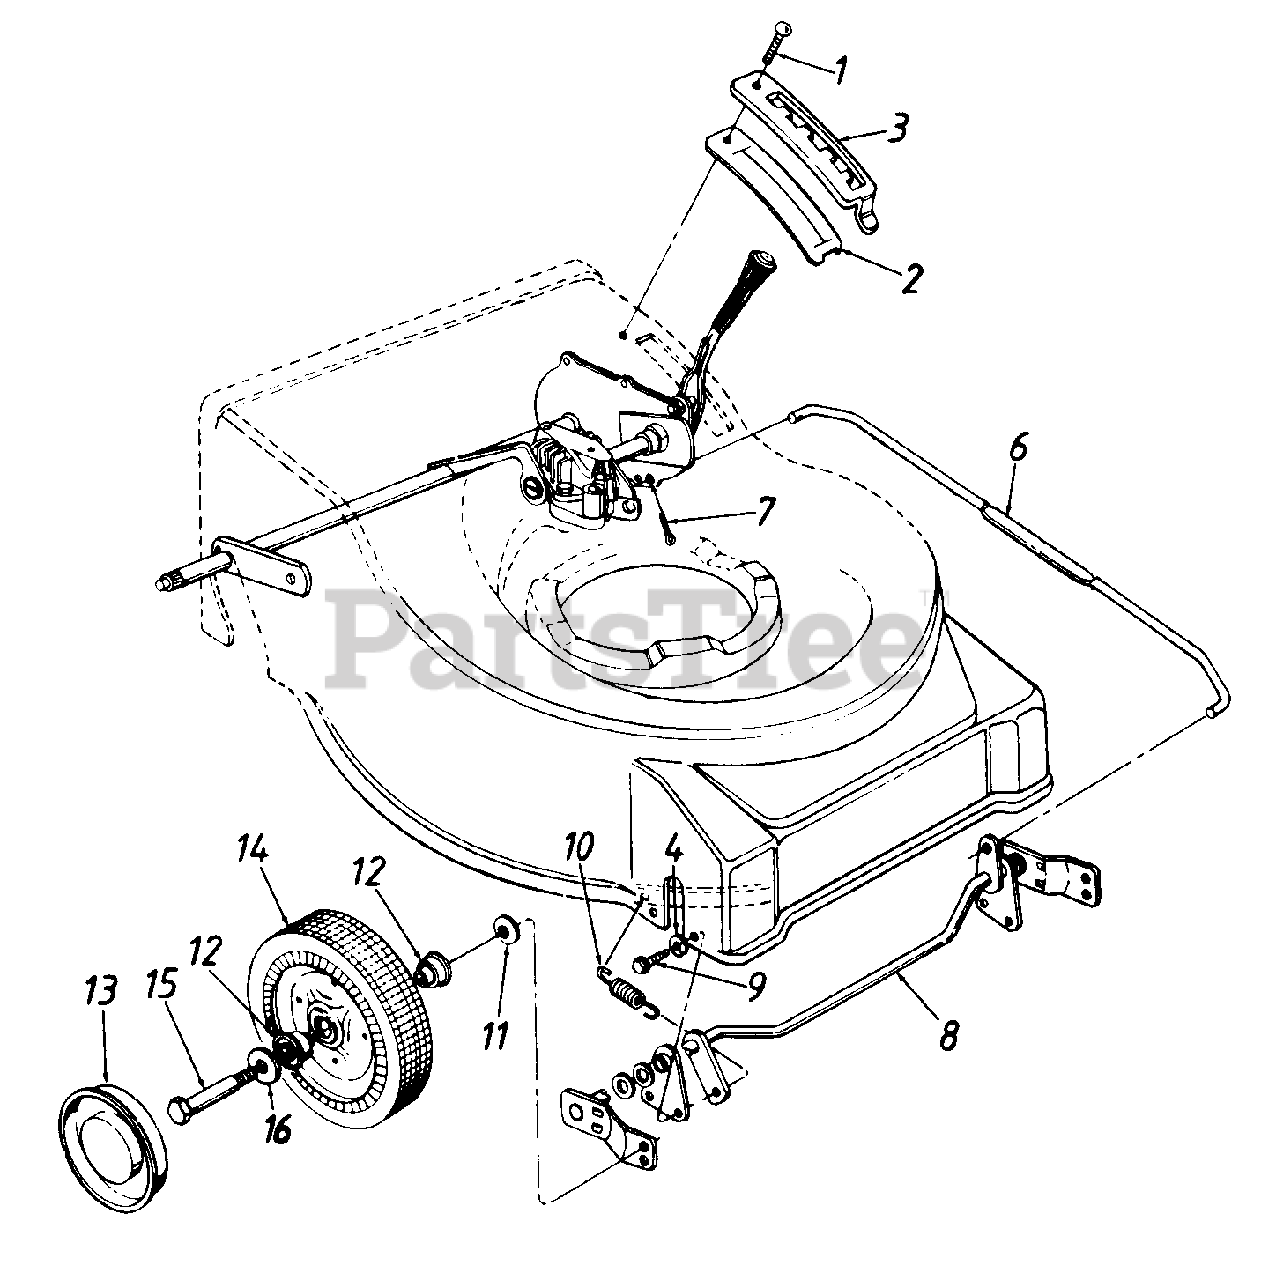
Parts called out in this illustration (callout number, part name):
1	Torx Mach. AB-Tap Scr. 1/4 x .62" Lg.
2	Height Adjustment Support
3	Height Adjustment Plate
4	L-Wash. 1/4" I.D.
6	Height Adj. Connecting Rod
7	Cotter Pin 3/32" Dia.
9	Hex L-Wash. Hd. AB-Tap Scr. 1/4 x.38" Lg.
10	Extension Spring 2.39" Lg.
11	Bell-Wash. .380" I.D. x .88" O.D.
12	Flange Ball Bearing 1/2" I.D.
13	Hub Cap
14	Wheel Ass'y. Comp.-Front
15	Shld. Bolt .498" Dia. x 1.45
16	Wave Wash. .53" I.D. x .78"
